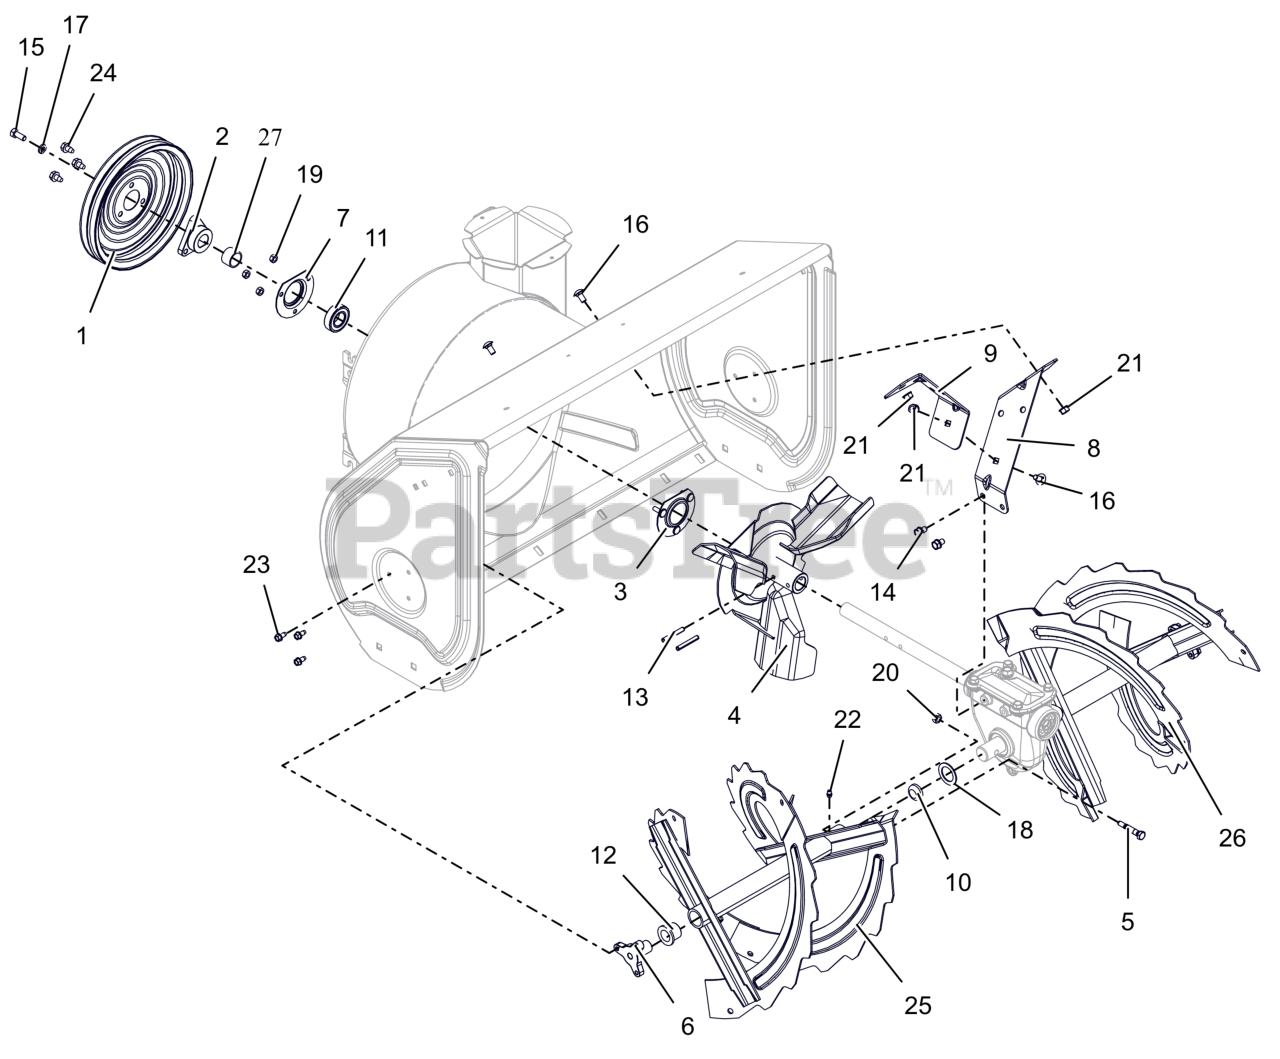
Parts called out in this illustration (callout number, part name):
1	PULLEY, SPIN FORM DUAL GROOVE
2	PULLEY HUB, D-BORE .87 PRO
3	BEARING FLANGE
4	IMPELLER, 3 BLADE-14"
5	SHEAR BOLT SERVICE ASSEMBLY
6	SUPPORT, RAKE BUSHING
7	BEARING FLANGE
8	BRACKET, GEARCASE SUPPORT - LH
9	BRACKET, GEARCASE SUPPORT - RH
10	PLUG, RAKE TUBE
11	BRG-BALL .876 X 1.750 X .50
12	BSHG-FLG, NY.778 ID X 1.018 OD
13	PIN-ROLL .250X1.75
14	BLT, SEMS .31-18X.50 G5 ZCC
15	BLT, HEX .31-24X.750 G5 ZCC
16	BLT,RHSSN.31-18X.625 G5 ZCCP30
17	WSHR, LK-HVY .312X.097 ZCC
18	WSHR, FLT 1.010X1.505X.062 ZCC
19	NUT,LK-CTR .25-20 GA ZCC
20	NUT,LK-CTR .31-18 GA ZCC
21	NUT-LK-TOP-FLG .312-18 GF ZCC
22	ZERK,FITTING .25X.125 DRIVE IN
23	SCR-TAP .25-20X.50 HWH ZCC
24	SCR,TAP .312-18X.50 HWH TR ZCC
25	RAKE, RH W/ZERK - 30"
26	RAKE, LH W/ZERK - 30"
27	BSHG,SPCR .895X1.065X.693
